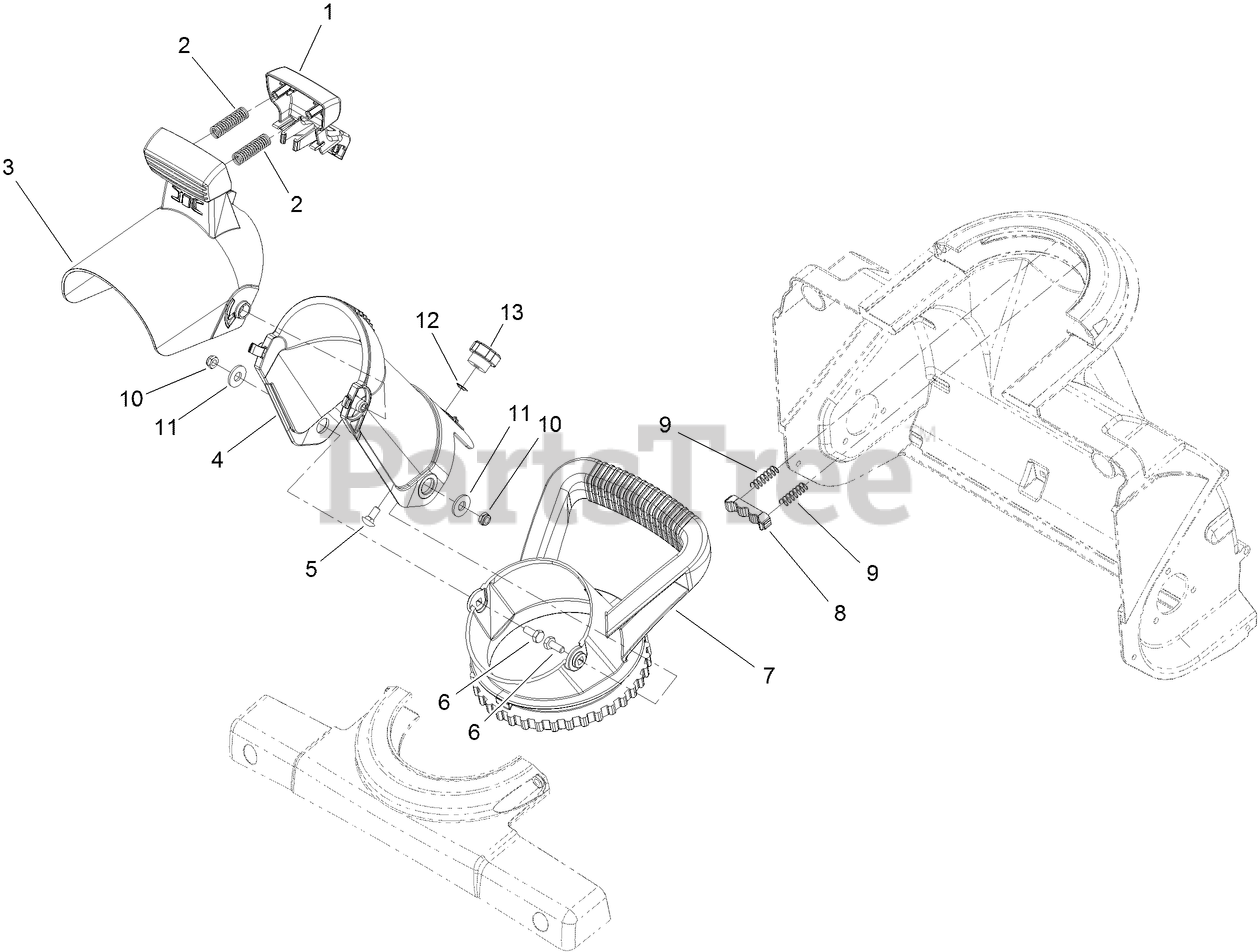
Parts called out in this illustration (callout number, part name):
1	TRIGGER-DEFLECTOR
2	SPRING-COMPRESSION
3	CHUTE DEFLECTOR ASM
4	CHUTE-DISCHARGE
5	BOLT-CARR
6	SCREW-HH
7	HANDLE-CHUTE
8	DETENT-CHUTE
9	SPRING-COMPRESSION
10	NUT-HEX
11	WASHER-PLAIN
12	PUSHNUT-RETAINER, BOLT
13	KNOB-CHUTE
